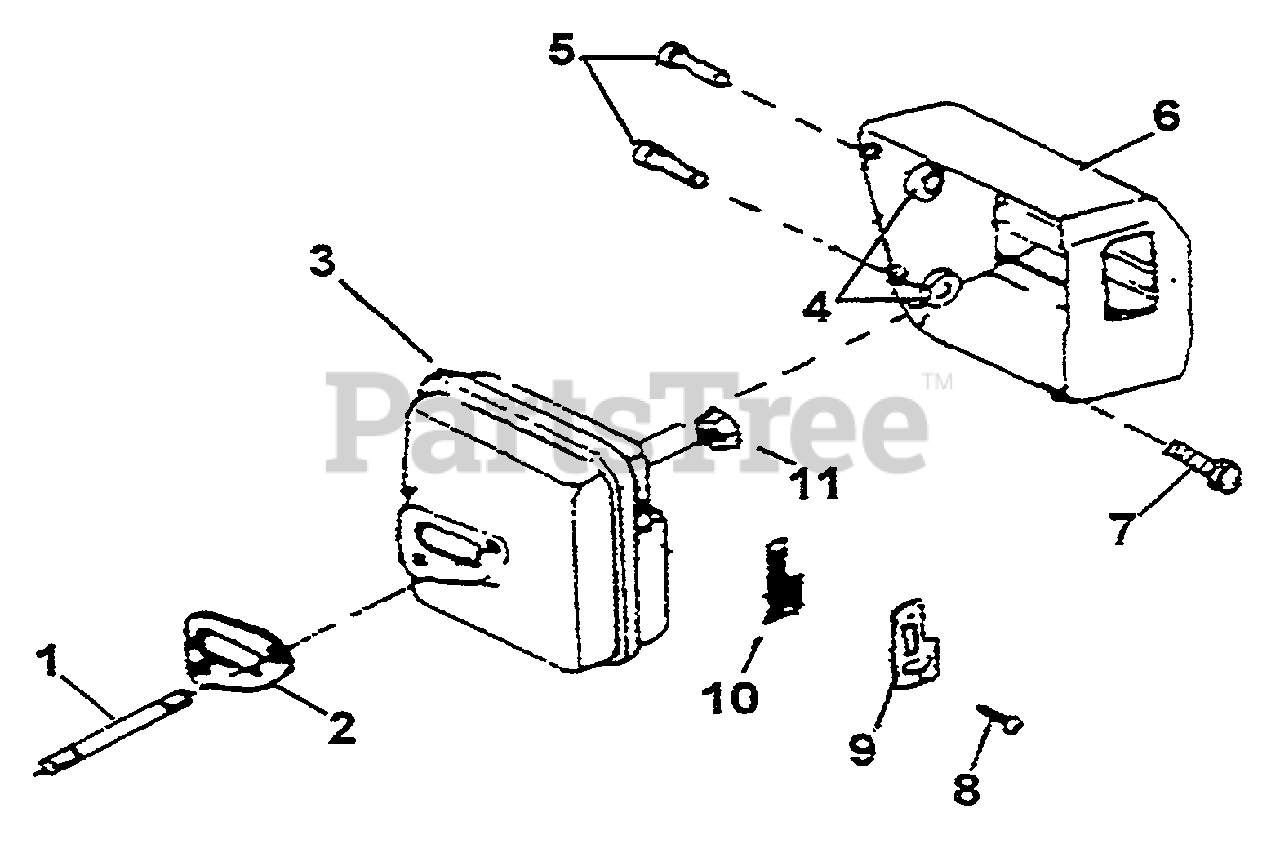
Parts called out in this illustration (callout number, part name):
2	GASKET, MUFFLER
3	MUFFLER ASSY
9	COVER SPARK ARRESTOR
10	SCREEN, SPARK ARRESTOR
